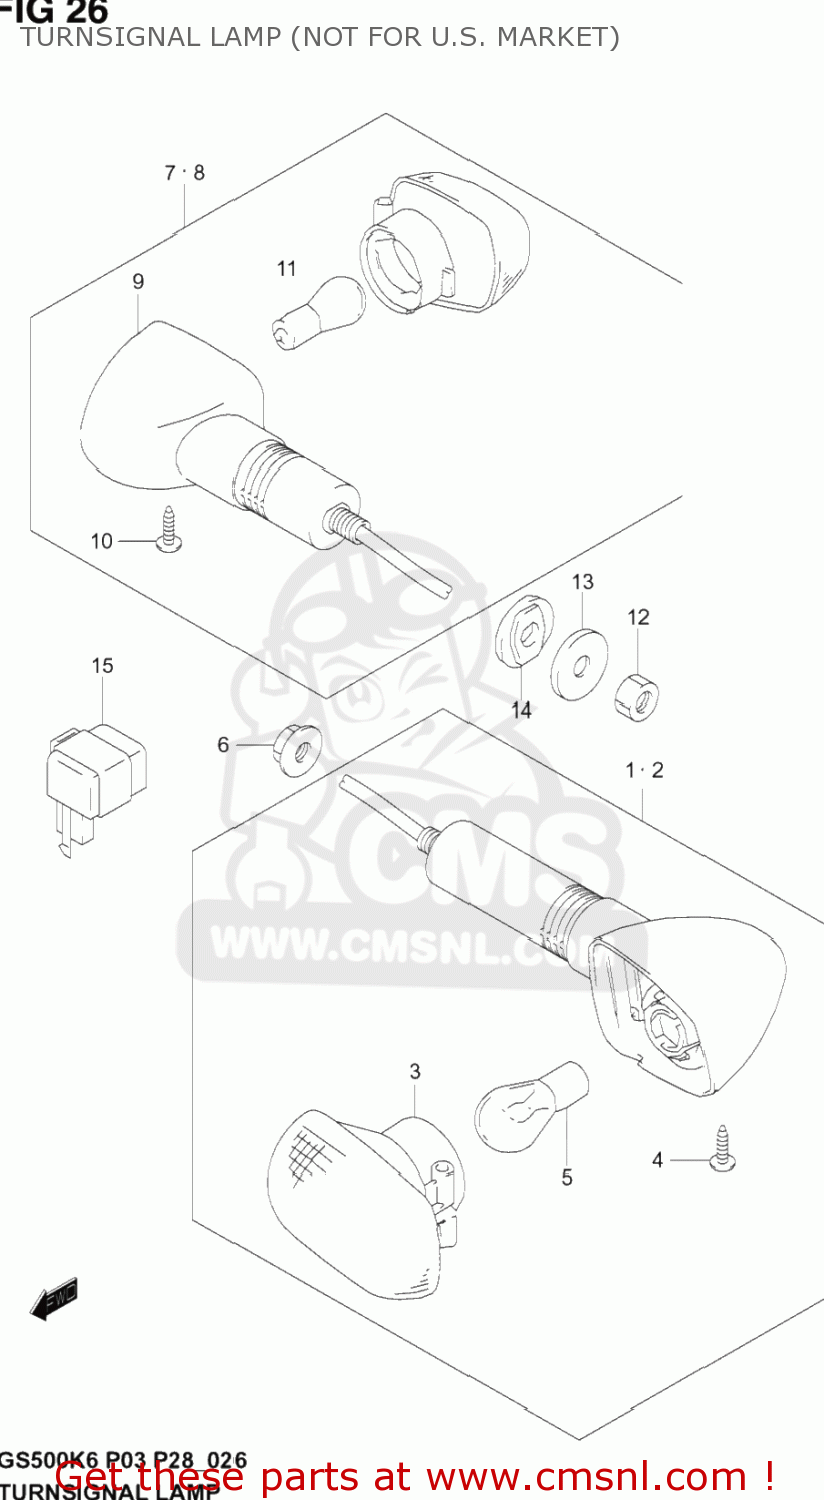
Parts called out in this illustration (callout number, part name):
1	TURNSIGN FR RH
2	LAMP ASSY, FRONT LH
3	LAMP UNIT
4	SCREW
5	BULB(12V21W)
6	NUT
7	LAMP ASSY REAR
8	LAMP ASSY REAR
9	LAMP UNIT
10	SCREW
11	BULB(12V21W)
12	NUT
13	WASHER(10.5X30X2.3)
14	SPACER,RR TURNSIGNAL
15	RELAY ASSY, TURNSIGNAL
